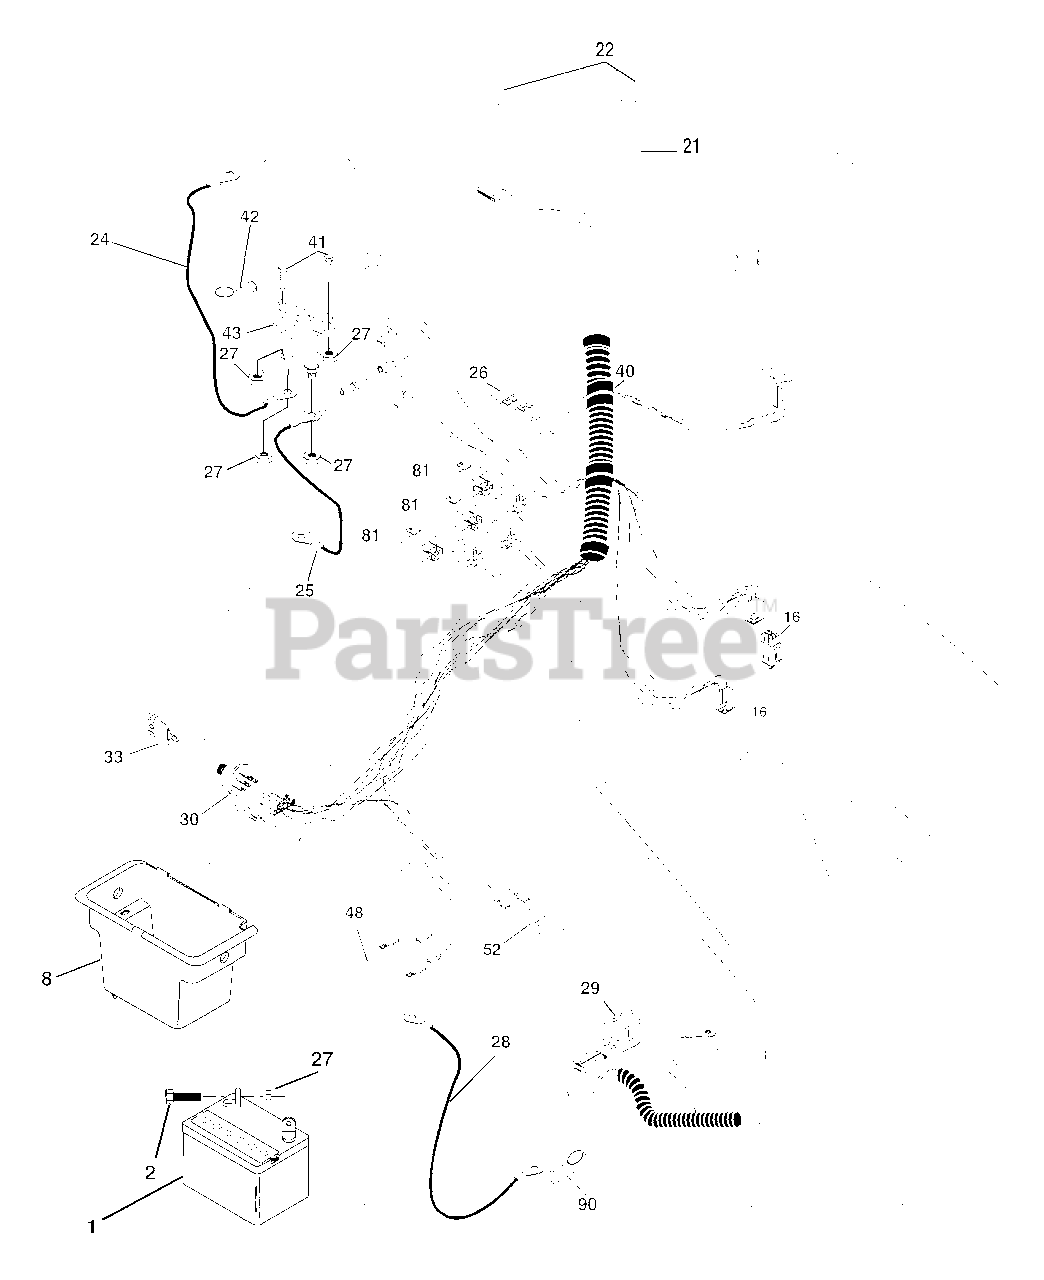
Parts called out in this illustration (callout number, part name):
1	Battery
2	Bolt Hex Hd 1/4-20unc X 3/4
8	Box Battery
16	Switch Interlock
21	Harness Asm Light W/4152j
22	Bulb Light #1156
24	Cable Battery 6 Ga 11" red
25	Cable Battery 6 Ga 44" red w/16 wire
27	Nut Keps Hex 1/4-20 Unc
28	Cable Ground 6 Ga 12" black
29	Switch Plunger Olive
30	Switch Ign Delta
33	Key Ign Molded Generic
40	Harness Ign.
41	Bolt Blk Fin Hex 1/4 - 20 x 1/2
42	Cover Terminal Red
43	Solenoid
48	Adapter Ammeter Rectangular
52	Protection Wire Loop
81	Relay Asm.
90	Cover Terminal Battery
